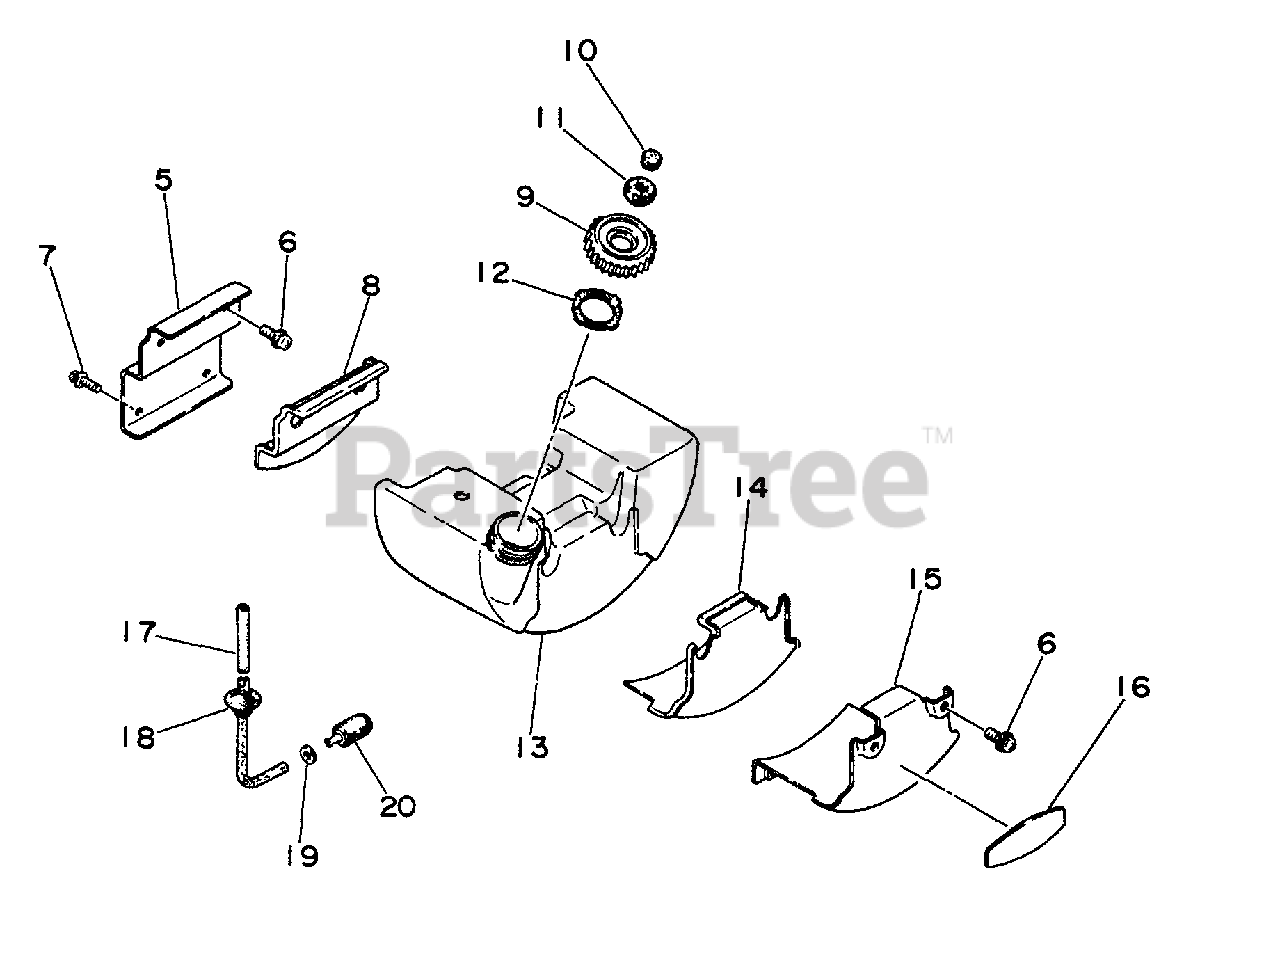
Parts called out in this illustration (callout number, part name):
5	BRACKET, FUEL TANK
6	SCREW 5×14
7	SCREW 4×14
8	CUSHION
9	CAP ASSY
10	FILTER, CHECK VALVE
11	VENT ASSY
13	TANK, FUEL
15	BRACKET, FUEL TANK
16	LABEL - ECHO
17	FUEL PIPE KIT
19	WASHER 5.5×12×0.8
20	FILTER, FUEL
